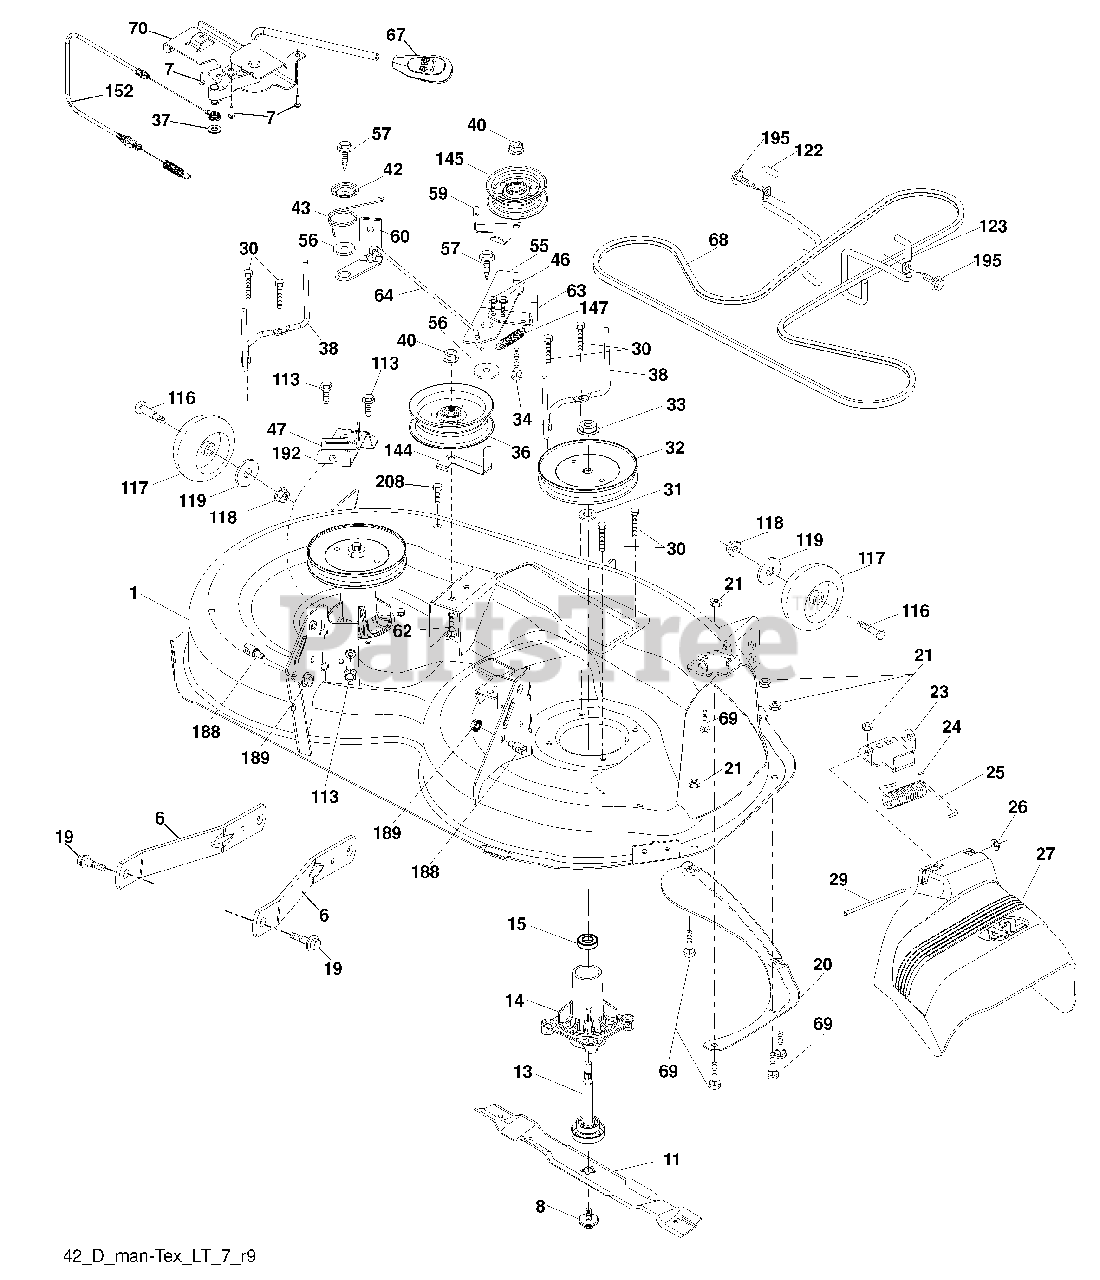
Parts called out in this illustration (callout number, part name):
1	Mower Housing
6	Arm Suspension
7	Screw #10 x .750 BOS Thread
8	Bolt/Washer Asm 7/16-20 unf
11	Blade, 42" Hi-Lift
13	Shaft Assembly, Mandrel
14	Housing, Mandrel
15	Bearing, Ball, Mandrel
19	Bolt, Shoulder
20	Baffle, Vortex
21	Nut, Crownlock 5/16-18 unc
23	Bracket, Deflector
24	Cap, Sleeve
25	Spring, Torsion, Deflector
27	Shield, Deflector
29	Rod, Hinge
30	Screw Thdrol Rolling Wsh Hd
31	Washer, Spacer
32	Pulley, Mandrel
33	Nut, Toplock, Flanged
34	Bolt Carr Sh. 3/8-16 x 1-1/2 Gr. 5
36	Pulley, Idler, Flat
37	Washer
38	Keeper Belt LH Mandrel
40	Nut, Lock Flg. 3/8-16 unc
42	Spring Torsion Brake
43	Spring Torsion Retainer
46	Screw Thd Roll 1/4-20 x 5/8
47	Bracket Clutch Cable
55	Arm, Idler
56	Spacer, Retainer
57	Screw 3/8-16 x 1
59	Guard, Tuv Idler
60	Arm Brake Mower
62	Bolt Rd Hd Sq Nk 3/8-16 unc x 2
63	Arm Brake Mower
64	Link Brake
67	Handle Clutch Cable
68	V-Belt
69	Bolt
70	Clutch Asm Manual
113	Screw 5/16-18
116	Bolt, Shoulder
117	Wheel, Gauge
118	Nut, Crownlock 3/8-1
119	Washer 13/32 x 7/8 x 14 Ga.
122	Keeper Belt Engine LH
123	Keeper Belt Engine RH
144	Keeper Belt
145	Pulley Idler
147	Spring Return
152	Manual Clutch Cable
188	Stud Fastener
189	Nut Lock Hex Flange
192	Bracket Brake Stand LH
195	Screw 3/8-16 x 3/4
208	Screw THDROL 3/8-16 x 1/2
